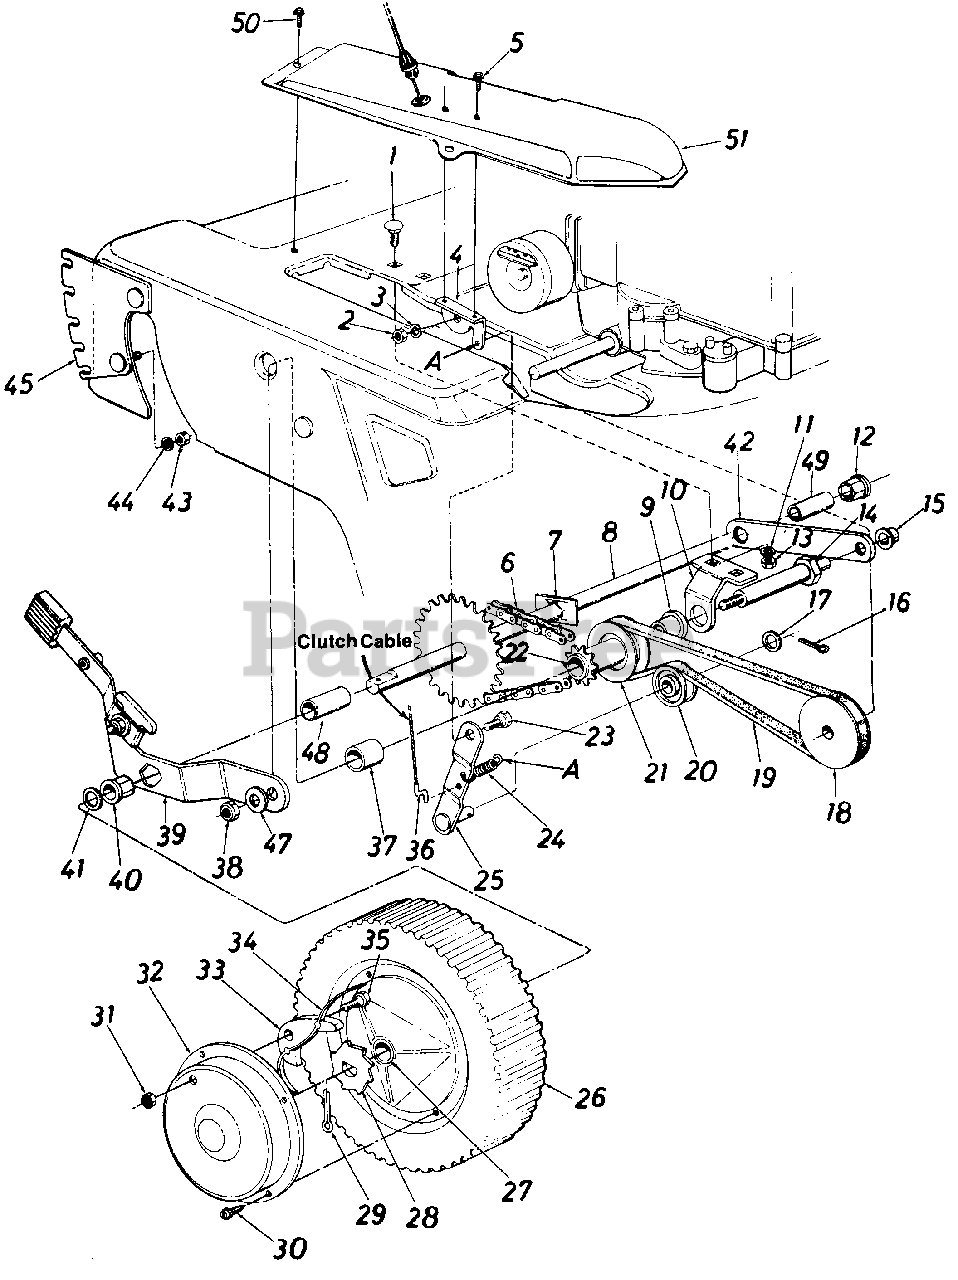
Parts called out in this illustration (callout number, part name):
1	Carriage Bolt 5/16-18 x .62" Lg.
2	Hex Nut 5/16-18 Thd.
3	L-Wash. 5/16" I.D.
4	Cam Bracket
5	Hex Wash. Hd. "AB" Tap L-Wash Scr. 1/4-20 x .62" Lg.
6	#48 Chain 1/2" Pitch x 31 Links
7	Push Clip .692 Dia.
8	Rear Shaft Ass'y.
9	Flange Bearing .631" I.D.
10	Bracket
11	L-Wash. 5/16" I.D.
12	Flange Bearing
13	Hex Nut 5/16-18 Thd.*
14	Shld. Bolt .625" Dia. x 3.380
15	Cap Speed Nut .50" Dia.
16	Cotter Pin 1/8" Dia. x 1.00" Lg.
17	Fl-Wash. .531 I.D. x .930 O.D. x .050
18	Engine Pulley
19	"V"-Belt 1/2" x 24" Lg.
20	Plastic Flat Idler
21	Pulley with 9 Tooth Sprocket Ass'y.
22	Sleeve Bearing .62" I.D. x .75" O.D. x .94 Lg.
23	Shld. Bolt .375" Dia. x .171 Lg.
24	Ext. Spring .33" O.D. x 1.12" Lg.
25	Idler Bracket Ass'y.
26	Rear Wheel Ass'y. Comp. 8.0 x 1.75
27	Flange Bearing .50" I.D.
28	Ratchet-Rear Wheel
29	Cotter Pin 1/8" Dia. x 1.00" Lg.
30	Pan Hd. 'AB" Tap Scr. #12 x .50" Lg.
31	Hex Ins. L-Nut 1/4-20 Thd.
32	Hub Cap
33	Pawl-Rear Wheel
34	Spring-Nylon
35	Shld. Bolt .342" Dia. x .268" Lg.
36	Drive Clutch Cable 59" Lg.
37	Spacer .635 I.D. x .88 O.D. x .910
38	Hex Jam Nut 5/16-18 Thd.
39	Pivot Bracket Ass'y.-R.H.
40	Flange Bearing
41	Fl-Wash. .531 I.D. x .93 O.D. x .050
42	Support Link
43	Hex Nut 5/16-18 Thd.
44	L-Wash. 5/16" I.D.
45	Index Plate Ass'y.-R.H.
47	Belleville Washer
48	Spacer
49	Spacer
50	Hex Wash. Hd. AB-Tap Scr. #10 x .50" Lg.
51	Belt Cover
